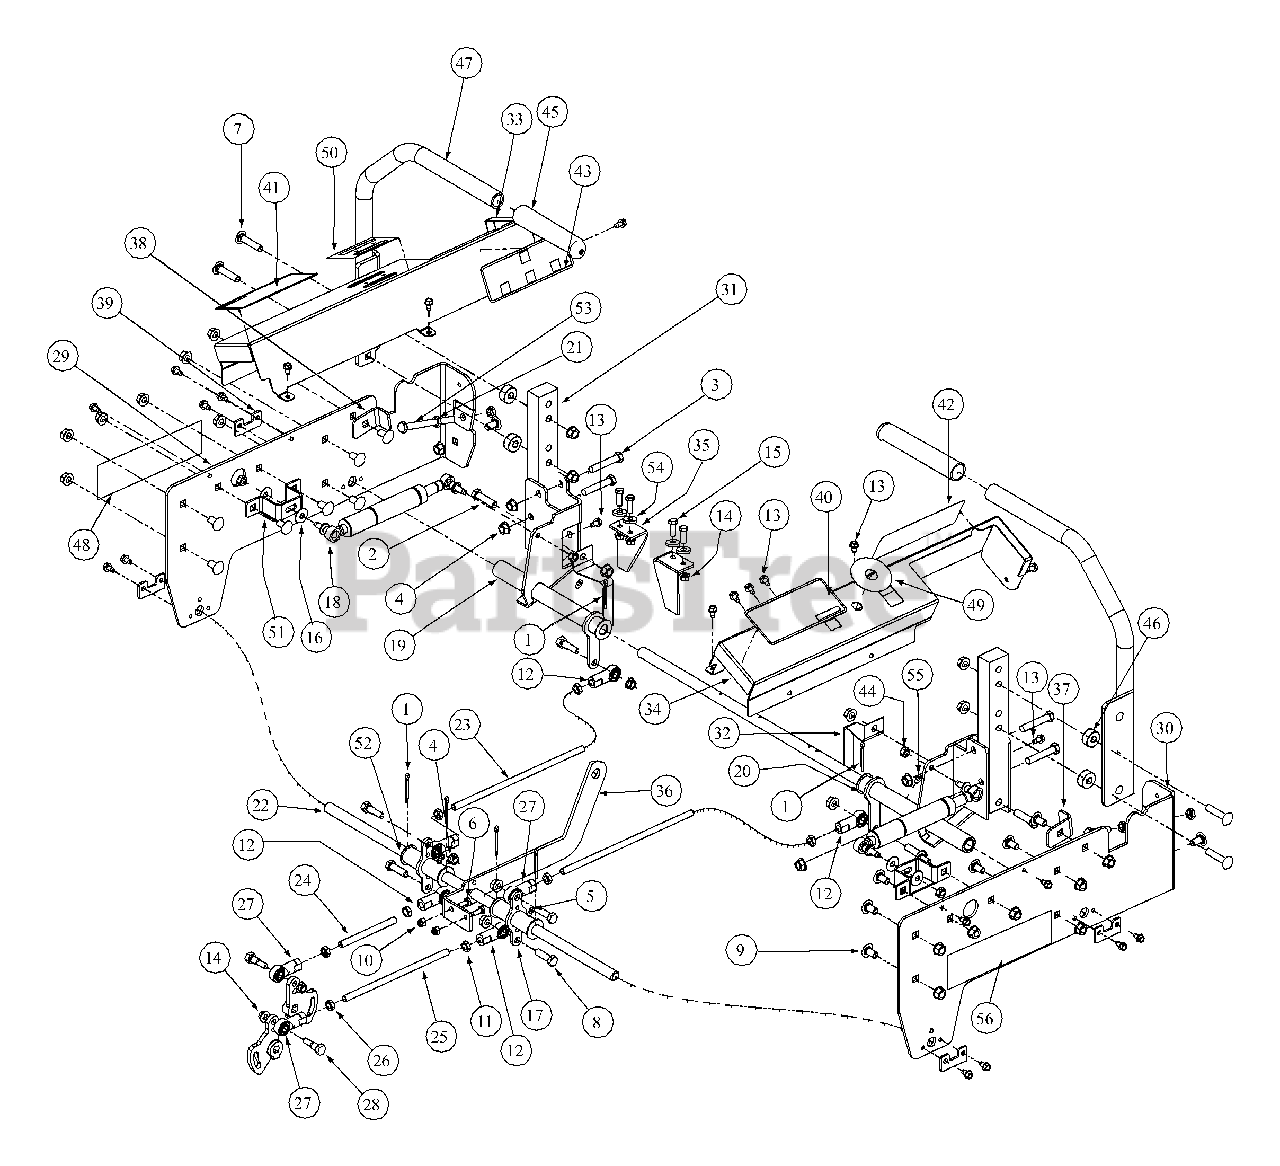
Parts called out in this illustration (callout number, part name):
1	Cotter Pin .125 Dia x 1.0
2	Hex Cap Screw, 3/8-16, 1.50
3	Hex Cap Screw, 3/8-16, 2.5
4	Hex Nut, 3/8-16, Lock Flange
5	Grease Fitting, 1/4-28 x 3/16
6	Hex Cap Screw, 1/4-20, .620
7	Hex Carriage Screw, 3/8-16 x 2
8	Hex Cap Screw, 3/8-16, 1.25
9	Carriage Bolt, 3/8-16 x .75
10	Lock Hex Nut, 1/4-20
11	Hex Jam Nut, 3/8-24
12	B/Joint, 3/8-24, Right Hand Female
13	Screw, TT, 1/4-20, 0.5, Hex Index Washer
14	Nut, Lock, Hex Flange, 5/16-18
15	Hex, Cap Screw, 5/16-18 x 3/4
16	Belle Washer, .325 x .930 x .045
17	Belle Crank Assembly,
18	Cylinder Return to Neutral
19	Hub Assy, Control LH Bearing
20	Hub Assy, Control RH Bearing
21	Nut, 3/8-16, Jam
22	Shaft Mounting Belle Crank
23	Rod Connector 3/8 OD x 10.125
24	Rod Connector, 3/8 OD x 4.28 LG LH
25	Rod Connector, 3/8 OD x 8.06 LG RH
26	Nut, 3/8-24, Jam, LH Third
27	B/Joint, 3/8-24, LH Female
28	Screw, Shoulder Control Rod
29	Side Panel, Control, Left
30	Side Panel, Control, Right
31	Mounting Handle
32	Lever, Safety Switch
33	Control Panel, LH
34	Control Panel, RH
35	Switch Mounting Bracket, Lapbar
36	Link Mounting Control Shaft, Bracket
37	Stop, RH
38	Stop, LH
39	Holder Shaft, Park Brake
40	Decal , Right Hand Console
41	Decal, Left Hand Console
42	Decal Right Hand Control
43	Decal, Left Hand Control
44	Nut, Hex, Center Lock, M8 x 1.2
46	Spacer, .406 ID x 1.00 OD x .38
47	Lapbar Handle, One Position
48	Side Label, LH
49	Label, Ingnition, 2.5 Diameter
50	Label, Control, Throttle and Choke
51	Bracket Assembly, Mount Dampener
52	Flat Washer, 5/8 Nylon
53	HHCS, 3/8-16, 3.00
54	Flat Washer, 5/16
55	Grease Fitting, 90°. 1/4-28
56	Side Label, RH
